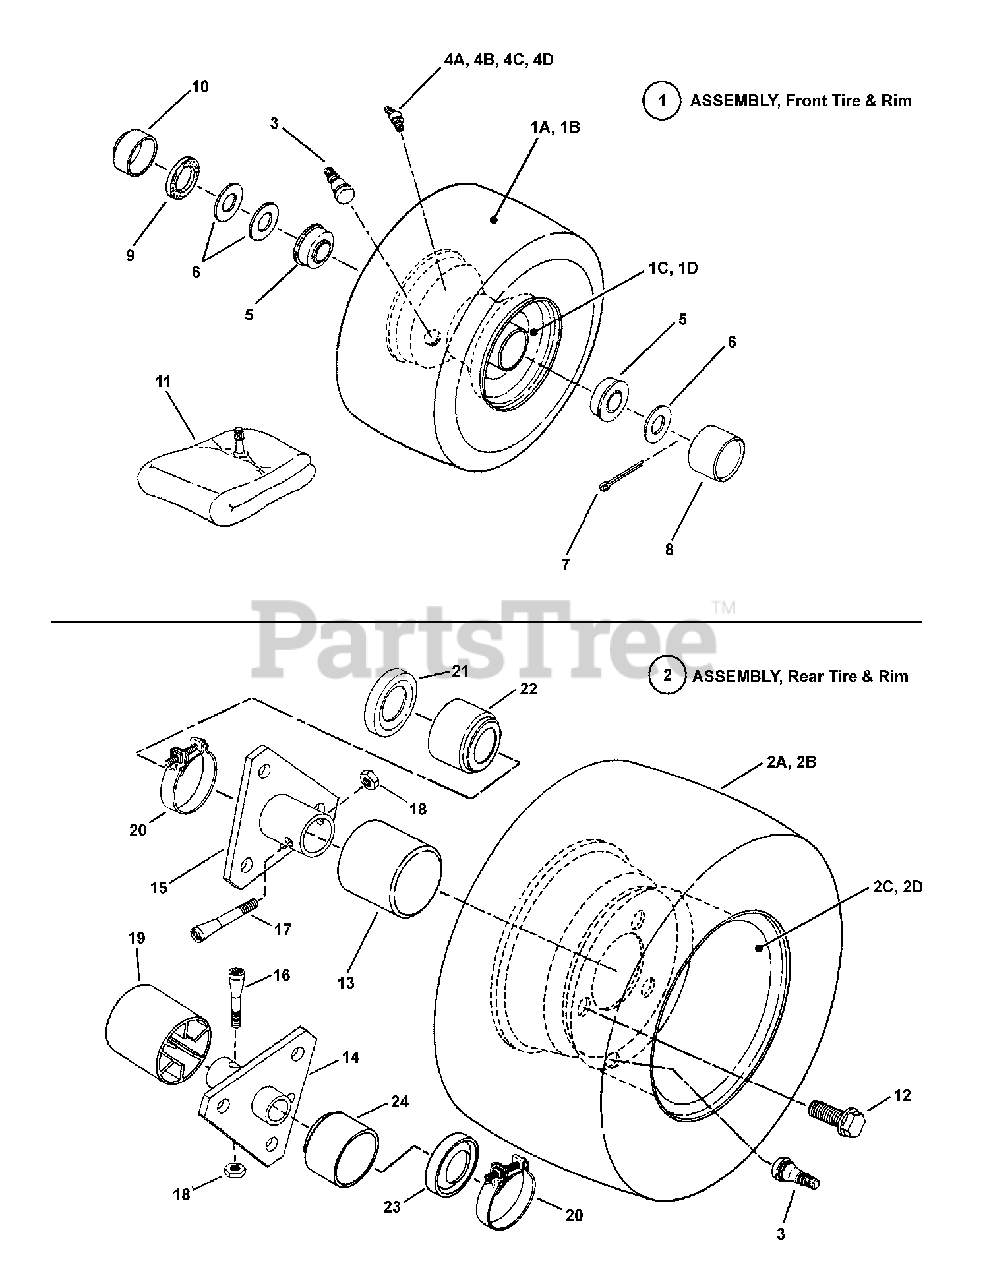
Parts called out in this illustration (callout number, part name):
1	ASSEMBLY, Front Tire & Rim (Complete)
1A	TIRE, 11 x 4.00-4 (Kenda)
1B	TIRE, 11 x 4.10-4, (Carlisle)
1C	RIM, (For 4.10/3.50 x 4 Tire)
1D	RIM
2	ASSEMBLY, Rear Tire & Rim
2	ASSEMBLY, Rear Tire & Rim (25 Models)
2A	TIRE, 16-6.50 x 8 (28 & 33 Models)
2B	TIRE, 16 x 4.80-8 Turf (25 Models)
2C	RIM, Extra Wide (For 16/7.50 x 8 Tire)
2D	RIM (4.80/4.00X8) 3 LUG
3	VALVE STEM, Snap In
4A	* LUBE Fitting, Straight (for 3/16 hole)
4B	* LUBE Fitting, Straight (for 1/4 hole)
4C	* LUBE Fitting, 90 Degree, Ball Check (for 1/4 hole)
4D	* LUBE Fitting, 90 Degree, Ball Check (for 5/16 hole)
5	BALL BEARING, Flange (3/4 I.D.)
6	WASHER, .77 x 1.13 x .06 Flat
7	COTTER PIN, 5/32 x 1"
8	HUB CAP
9	FELT SEAL
10	CAP, Dust
11	TUBE, Inner (For 4.10/3.50 x 4 Tire)
12	BOLT, 1/2-20 x 3/4 Lug, GR 5
13	HUB CAP, R.H. (1.35 ID x 2.25) (Short Axle)
14	HUB, Wheel LH, 3 Hole 3/4 ID
15	HUB, Wheel RH, 3 Hole 1 ID
16	BOLT, 5/16-24 x 1-5/8 Tapered (Left Hand)
17	BOLT, 5/16-24 x 2 Tapered (Right Hand)
18	NUT, 5/16-24, Hex Crown Lock,GR C, Zinc/Clear
19	HUB CAP, L. H. (.975 ID x 2.25) (Long Axle)
20	CLAMP, Boot, 2"
21	SEAL, 1.22 ID x 1.875 OD
22	CAP, Seal 1.0 ID x 1.67 OD
23	SEAL, OIL .750 ID x 1.832 OD
24	CAP, Seal 3/4 ID x 1.875 OD
